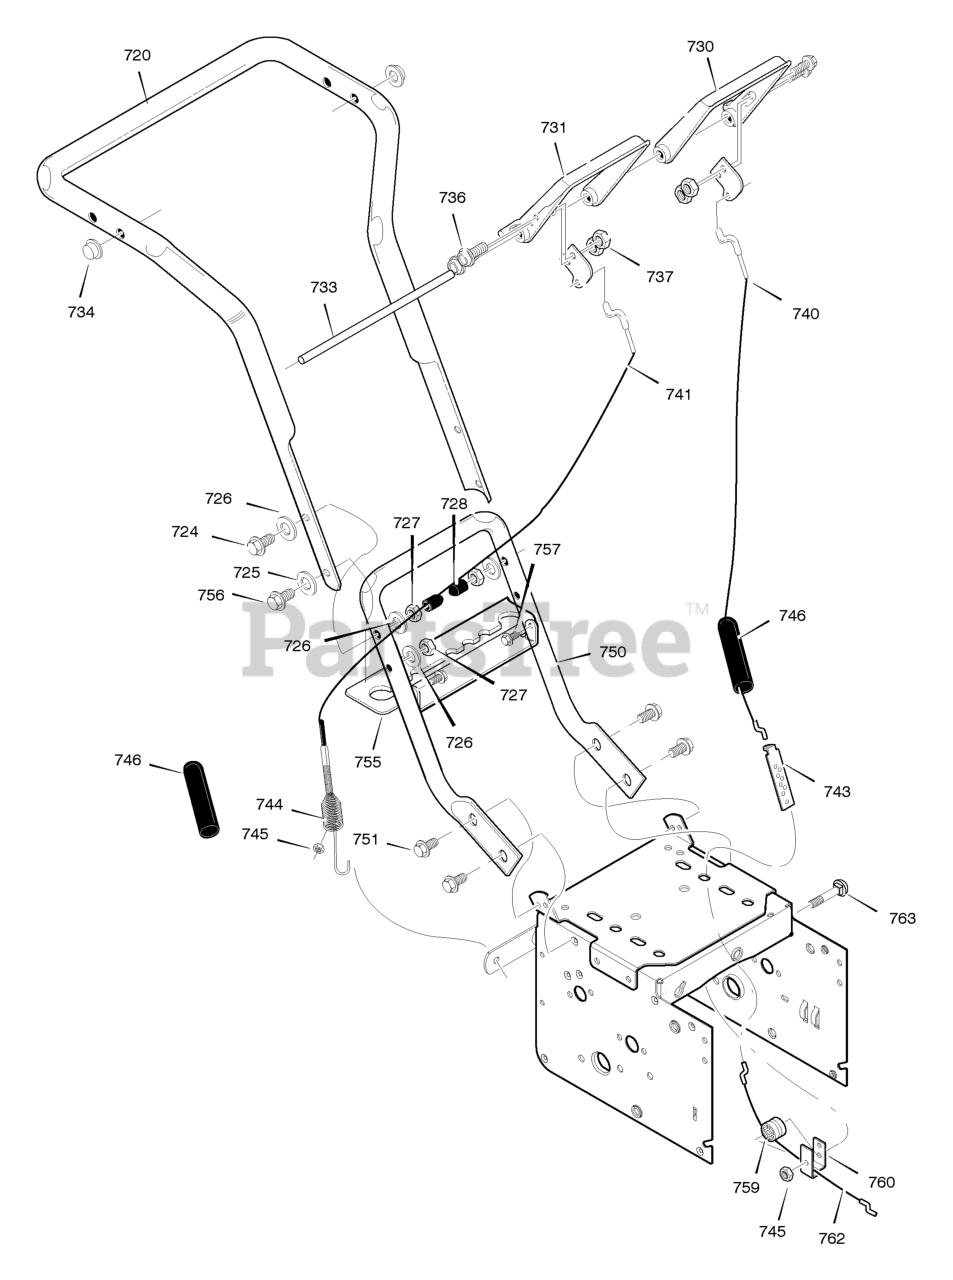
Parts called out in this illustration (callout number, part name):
724	SCREW 5/16-18 x 2.75
725	WASHER, FLAT
726	WASHER
727	NUT 5/16-18
728	PLASTIC-STOP
730	CLUTCH, LEFT HANDLE CONTROL
731	CLUTCH, RIGHT HANDLE CONTROL
733	ROD, PIVOT HANDLE
734	PUSH ON CAP
735	PLATE, CABLE PIVOT
736	SCREW 1/4-20 x 0.88
737	NUT 1/4-20
740	CABLE, CLUTCH
741	CABLE, AUGER CLUTCH
743	BRKT, CABLE ADJUST
744	SPRING, AUGER CLUTCH
745	LOCKNUT
746	BOOT, CLUTCH SPRING
750	HANDLE, LOWER
751	SCREW 51/16-18 x 0.75
752	WASHER
755	BRACKET, GEAR SELECTOR
756	SCREW, .31-18 x 2.00
757	SCREW, 1/4-20 X 0.62
759	SPOOL-CABLE, AUGRT CLUTCH
760	BRACKET, CABLE SPOOL YZ
762	CABLE, LOWER DRIVE 12"
763	BOLT, HEX 1/4-20 X 1.50 YZ
